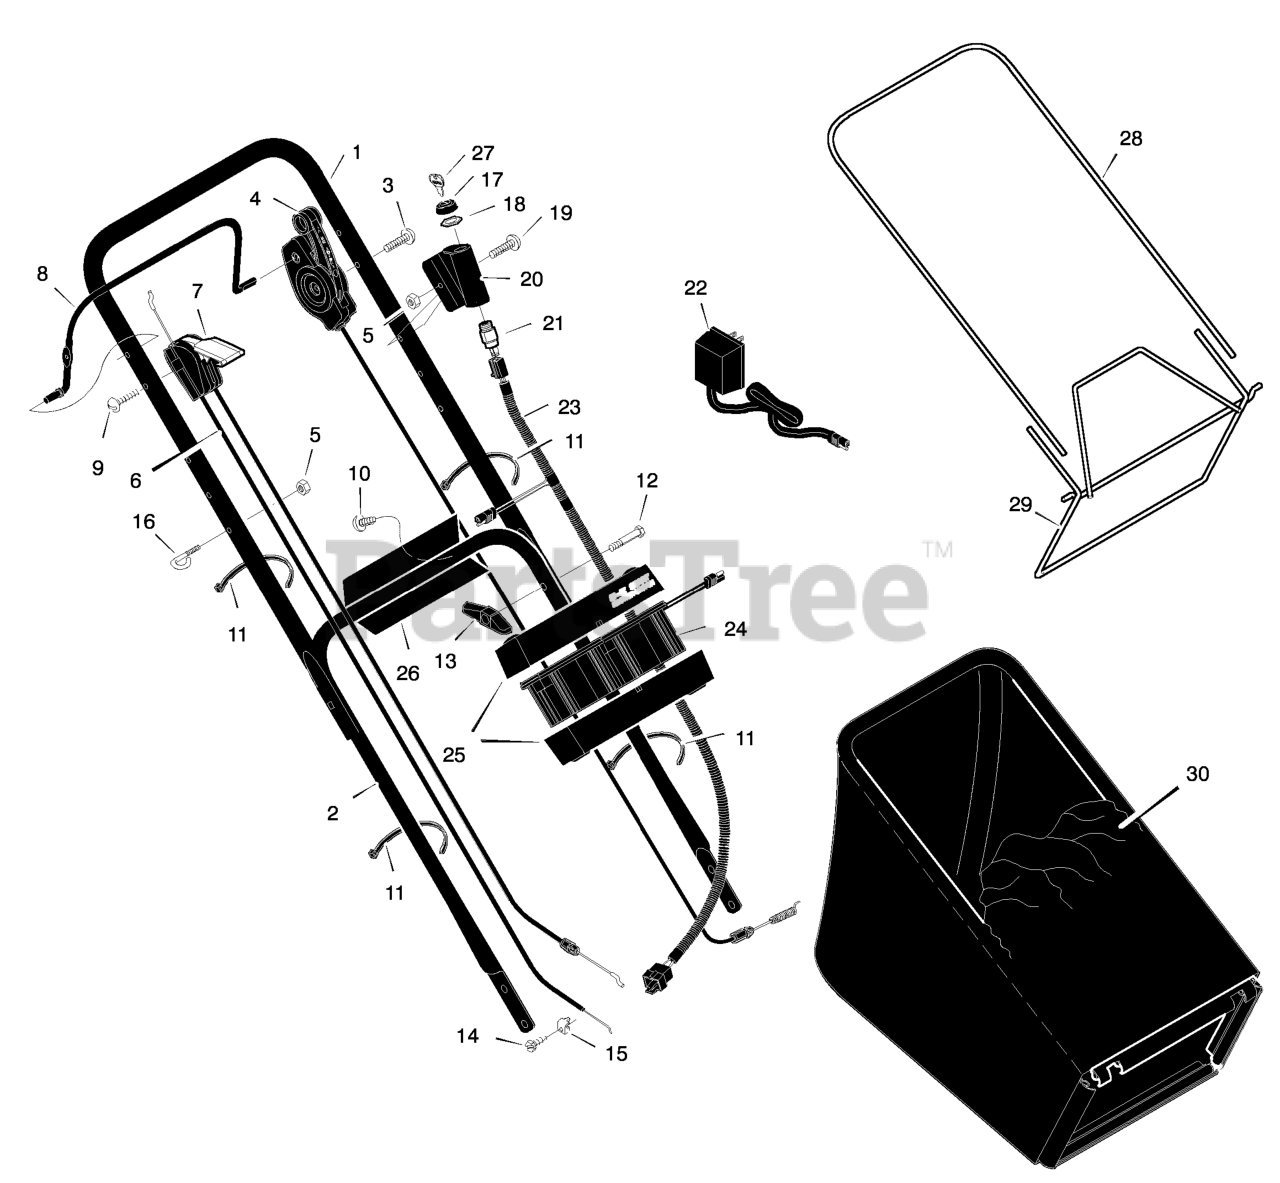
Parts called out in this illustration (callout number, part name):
1	Handle, Upper
2	Handle, Lower
4	Control, Drive
5	Locknut
6	Cable, Stop
7	Throttle Control
8	Engine Stop Lever
11	Fastener, Cable
13	Knob
16	GUIDE, ROPE
17	Cap
18	Nut
20	Cover, Ignition
21	Switch Ignition & Key
22	Charger, Battery
23	Harness, Wiring
24	Battery
25	Case, Battery
26	Bracket, Battery
27	Key, Ignition
28	Frame, Top
29	Frame Assembly
30	Bag, Cloth
